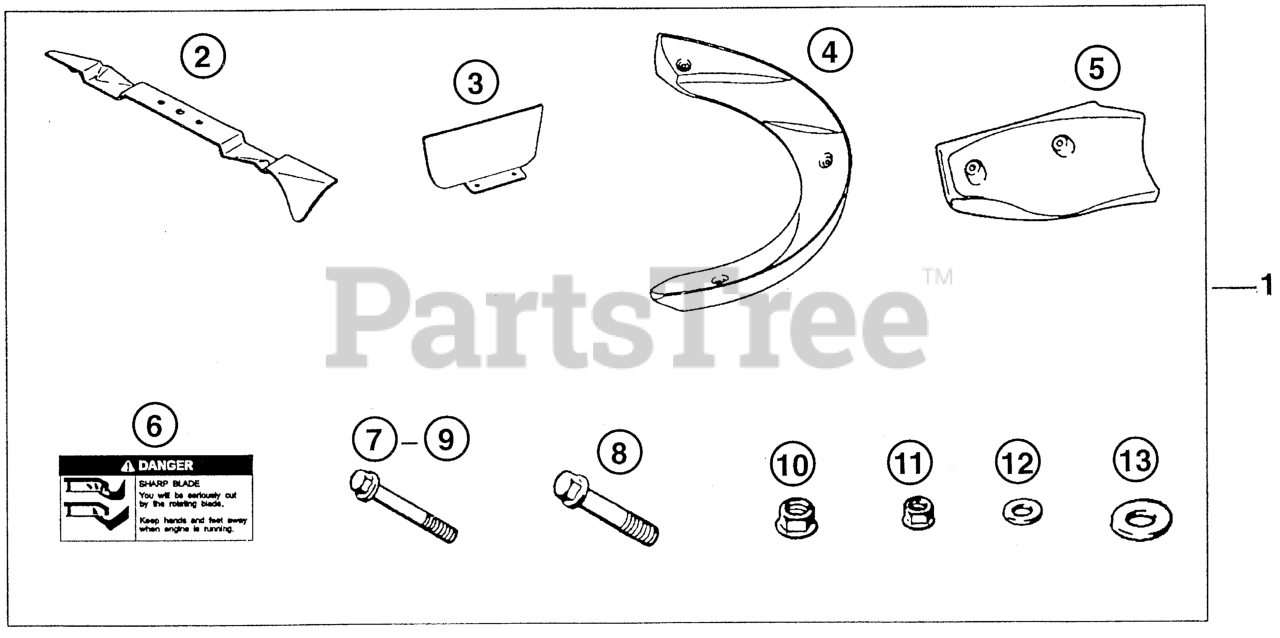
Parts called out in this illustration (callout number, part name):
1	MULCHING KIT
2	BLADE, MULCHING (NOT AVAILABLE)
3	PLATE, COVER (NOT AVAILABLE)
4	GUIDE A, SWIRL (NOT AVAILABLE)
5	GUIDE B, SWIRL (NOT AVAILABLE)
6	LABEL A, WARNING (ENGLISH)
7	BOLT, FLANGE (6X40)
8	BOLT, FLANGE (8X35)
9	BOLT, FLANGE (6X55)
10	NUT, SELF-LOCK (8MM)
11	NUT, SELF-LOCK (6MM)
12	WASHER, FLAT (6MM)
13	WASHER, FLAT (8MM)
